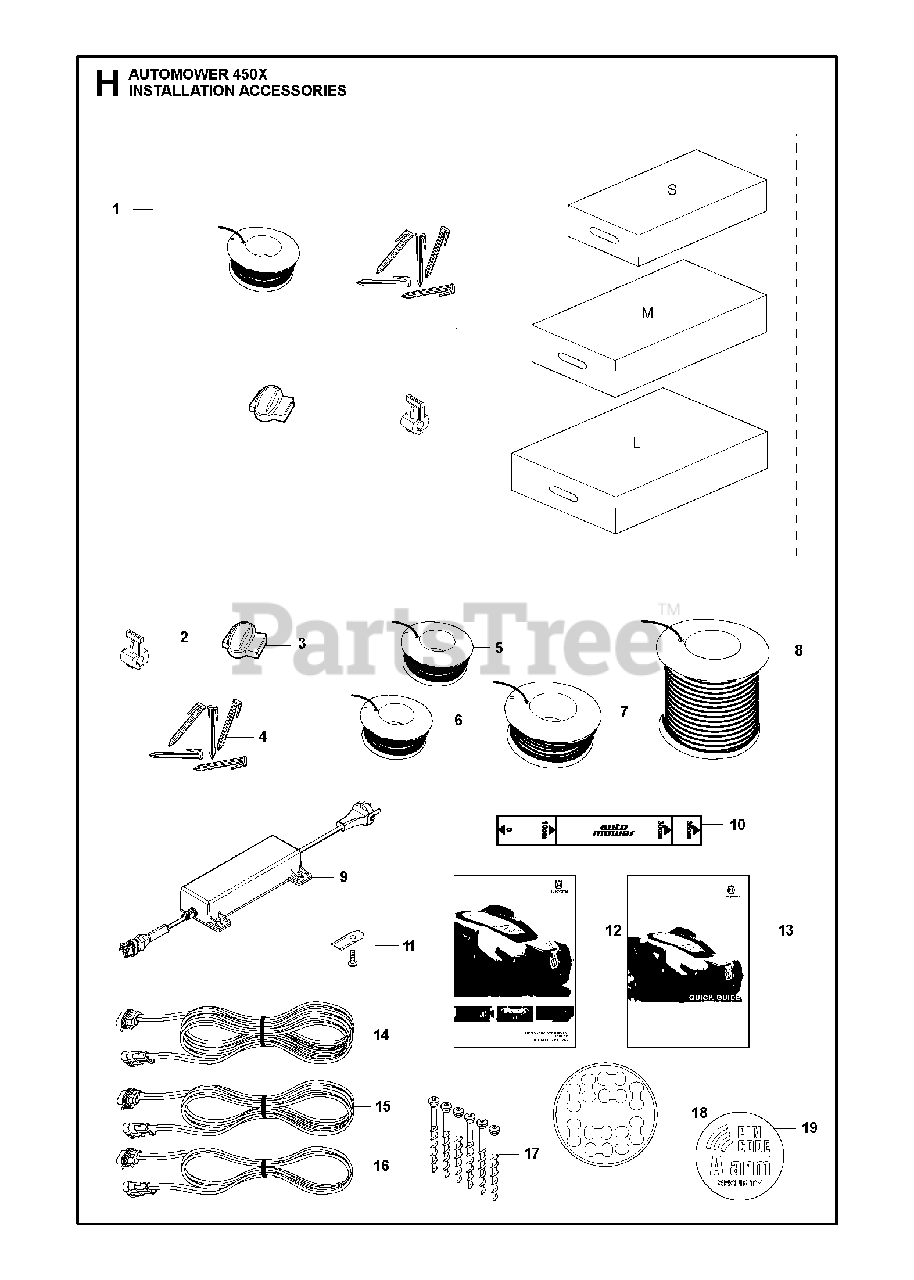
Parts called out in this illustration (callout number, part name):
1	SMALL AUTOMOWER INSTA
1	Automower Install, Medium
1	LARGE AUTOMOWER INSTA
2	BRAKER
2	Connector, 5 Pcs Blist
3	SPLICE KIT
3	Splicer Coupler, 5 Pcs
3	Splicer Coupler, 100 P
4	STAPLE 100 PCS BLISTE
4	Staples, 100-Pack
5	WIRE 50M STANDARD �2.7MM,BLIST
5	WIRE BOUNDARY 150M
5	WIRE 150M BLISTER
6	WIRE 250M
7	Wire, 500M
8	Wire, 800M
9	POWER UNIT POWER SUPPLY UNIT 7
10	RULER / CENTIMETERS
11	Blade Set, 9 Piece
11	Blade Set, 45 Piece
11	Blade Set, 300 Piece
14	Low Voltage Cable
15	Low Voltage Cable
16	Low Voltage Cable
17	SCREW KIT CS
17	SCREW 3 PCS, BLISTER PACK
18	STICKER CABLE MARKERS KIT 10PC
19	LABEL SECURITY
